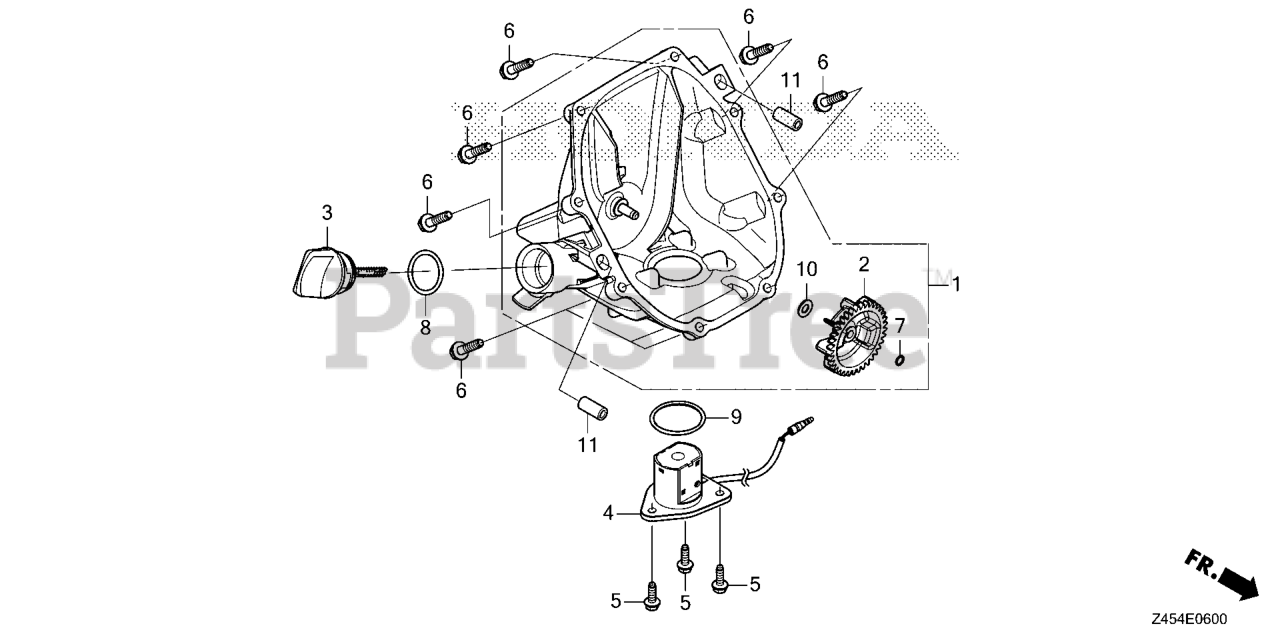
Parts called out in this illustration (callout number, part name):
1	COVER ASSY. (0000)
2	SLINGER, OIL
3	CAP, OIL FILLER
4	SW ASSY., OIL LEVEL
5	BOLT, FLANGE (5X14) (CT200)
6	BOLT, FLANGE (6X25) Use up to Engine SN 2056819.
7	CLIP, GOVERNOR HOLDER
8	O-RING (25.5X3)
9	O-RING (34.6X2.5)
10	WASHER, PLAIN (6MM)
11	PIN, DOWEL (8X20)
